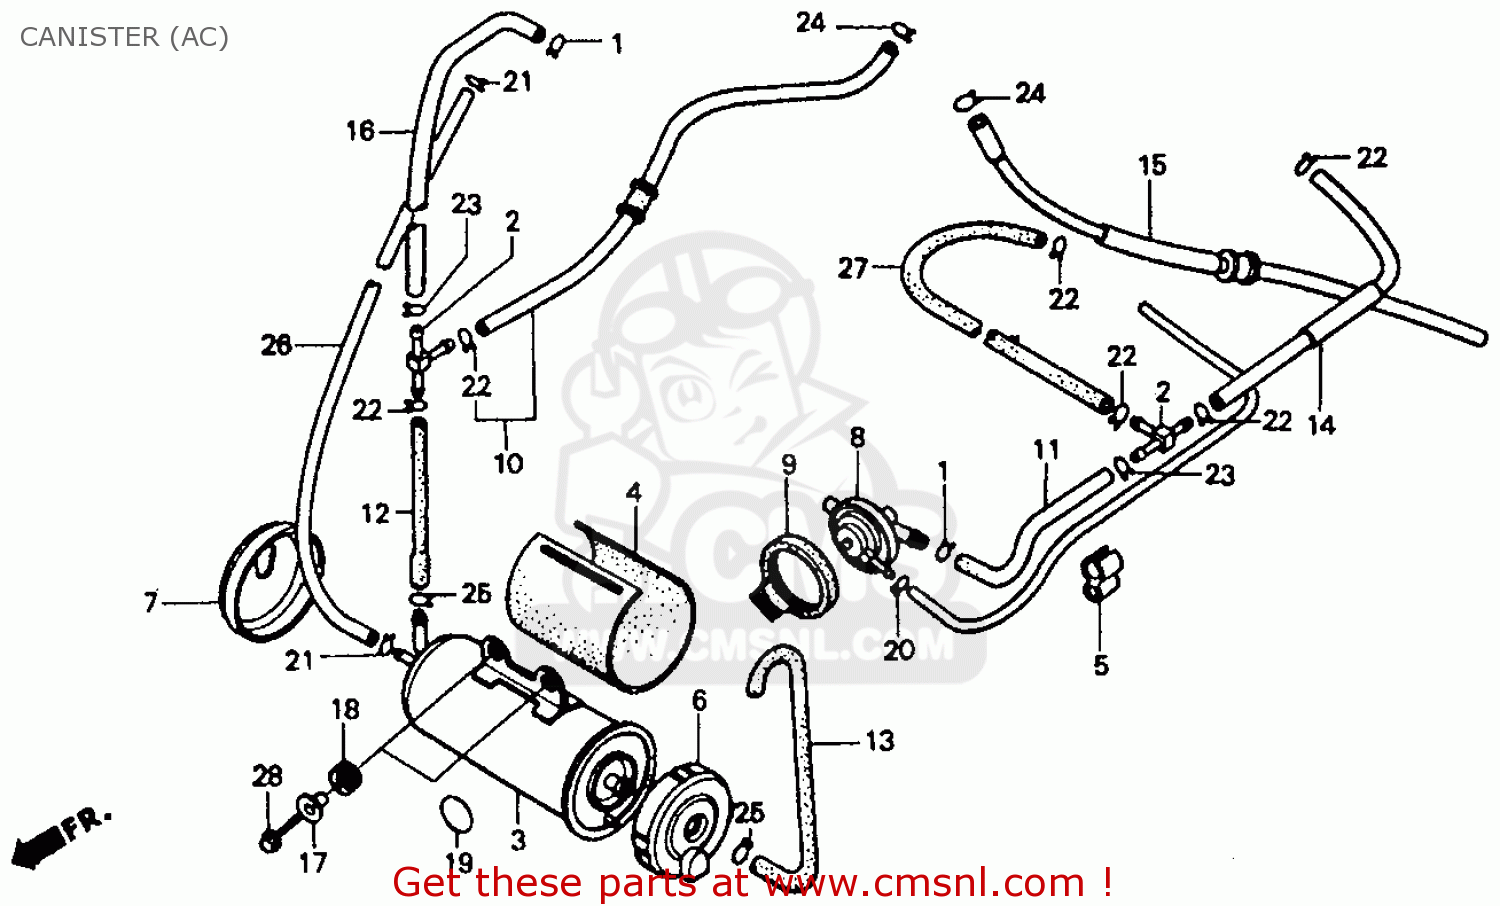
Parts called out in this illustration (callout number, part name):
1	CLIP,P.C.V.TUBE
2	JOINT,FUEL TUBE
3	CANISTER COMP.
4	COVER,CANISTER
5	CLIP, TUBE
6	COVER A,CANISTER
7	COVER B,CANISTER
8	VLV,PURGE CONTL.
9	RUB,PCV MT
10	TUBE ASSY.
11	TUBE A, PURGE
12	TUBE, CANISTER
13	TUBE, AIR
14	TUBE, RR.
15	TUBE ASSY.,AIR VE
16	TUBE, PURGE LINE
17	COLLAR,SETTING
18	RUBB,LIGHT MOUNT
19	LABEL, JACK WARNING
20	CLIP B7,TUBE
23	CLIP B12,TUBE
24	CLIP,TUBE,B12.5
25	CLIP,P.C.V.TUBE
26	BULK TUBE,TA 45X1
27	BULK TUBE,TA 55X8
28	BOLT,FLANGE,6X25
